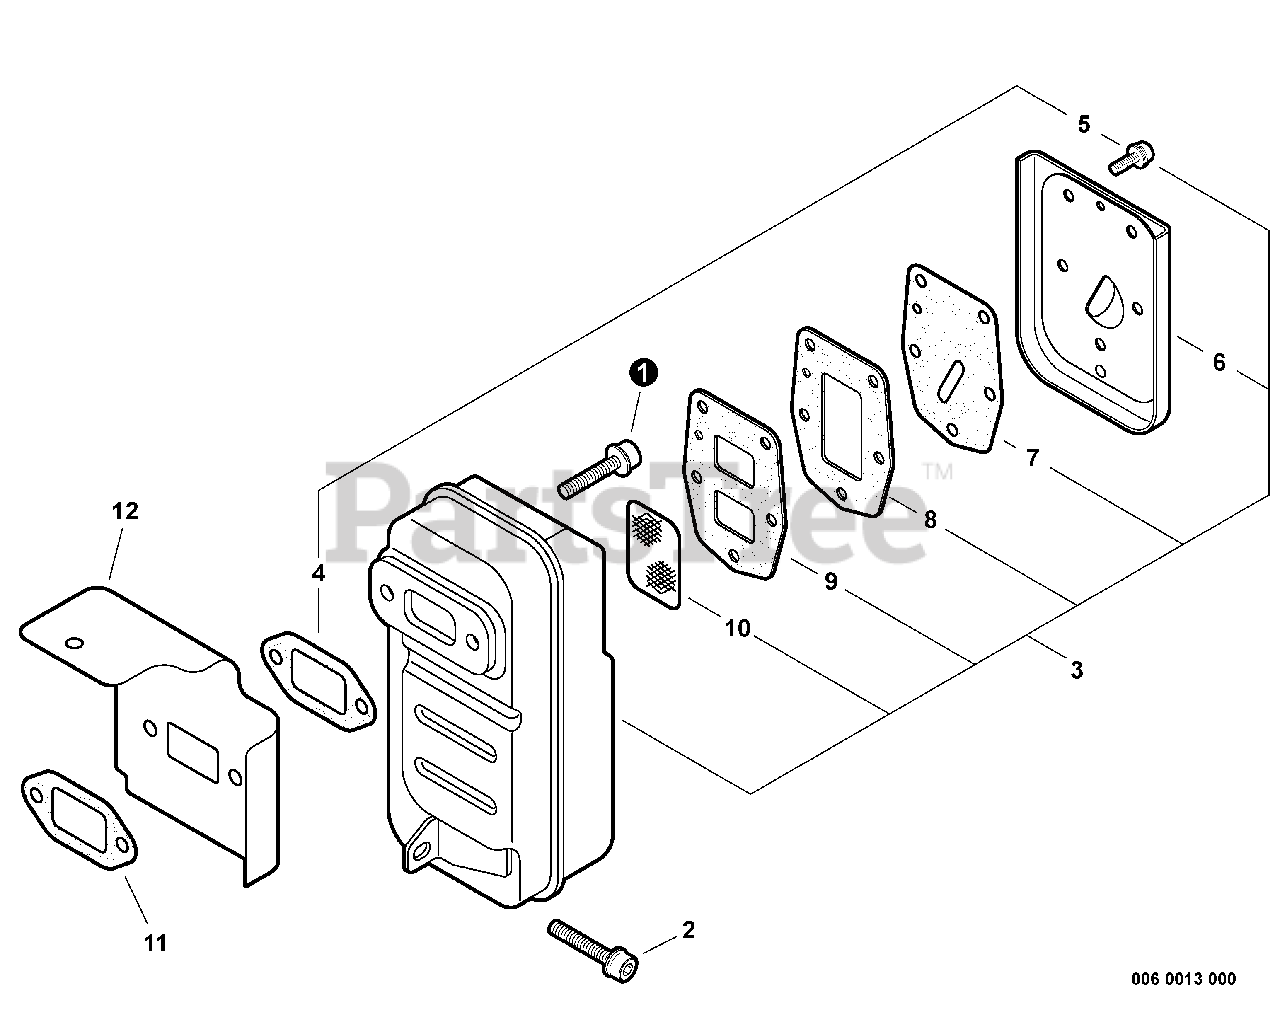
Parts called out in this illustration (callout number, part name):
1	BOLT 6×20
2	BOLT 5×20
3	MUFFLER ASSY
4	GASKET, MUFFLER
5	SCREW 4×14
6	GUIDE, EXHAUST
7	GASKET, EXHAUST
8	GASKET, EXHAUST
9	GASKET, EXHAUST
10	SCREEN, SPARK ARRESTER
11	GASKET, MUFFLER
12	COVER, ENGINE - EXHAUST
